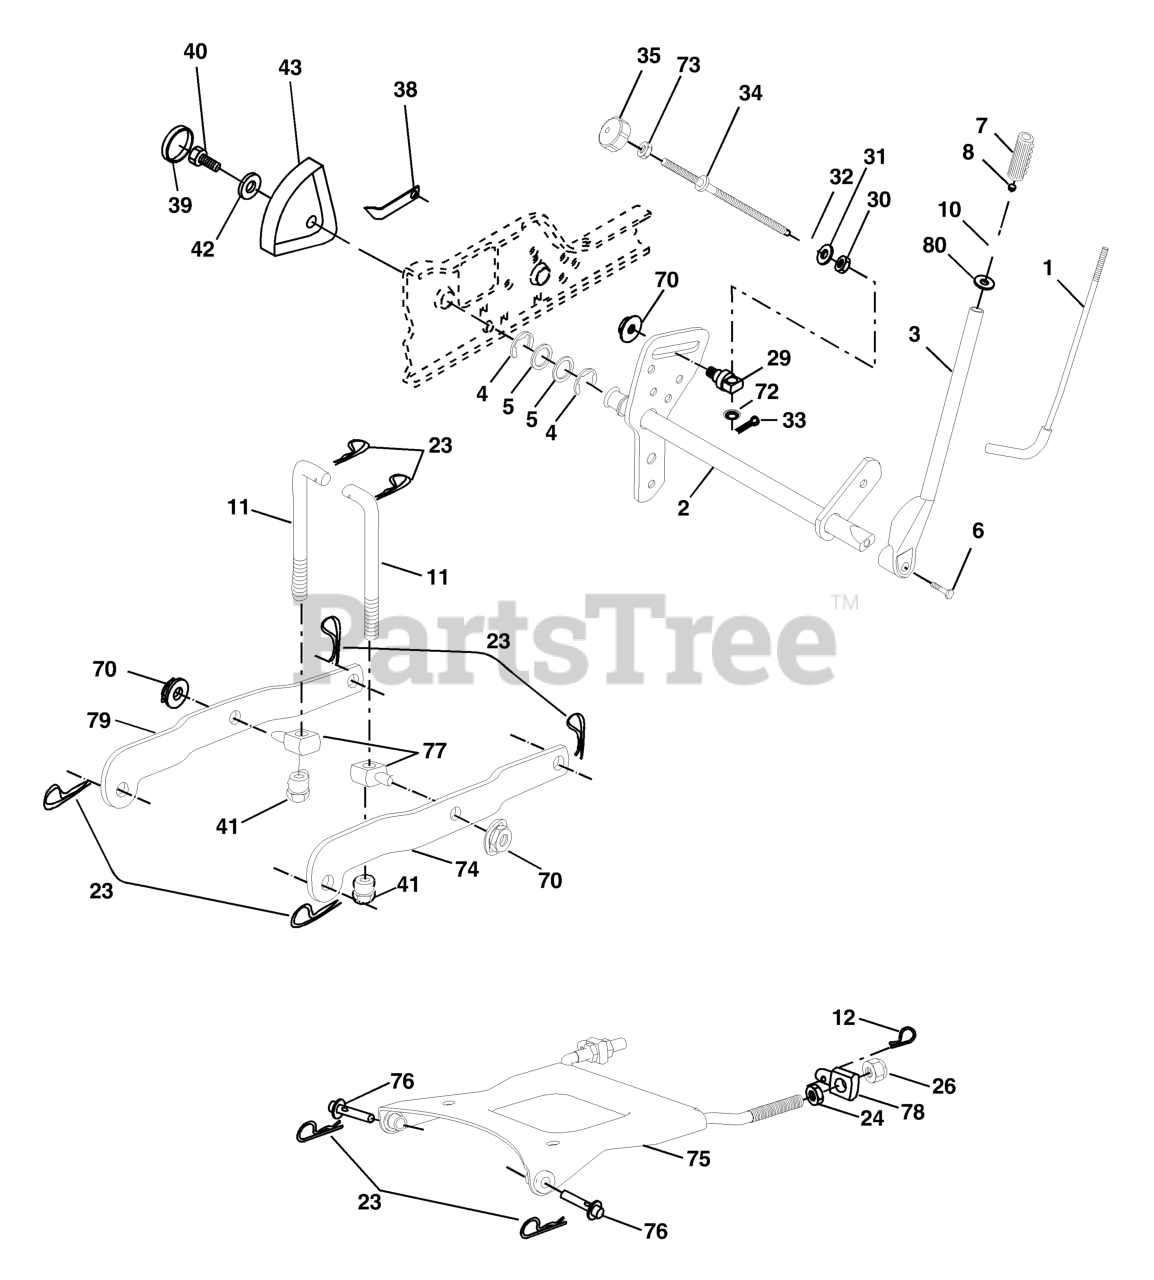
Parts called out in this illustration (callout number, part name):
1	LEVER ROD LT
2	SHAFT ASM., LIFT VGT
3	LEVER ASSY-LIFT RH
5	Washer 29/32 x 1-1/4 x 16 Ga.
6	Bolt, Fin Hex 3/8-16 x 1-1/2
7	GRIP HANDLE
8	PLUNGER BUT KIT
9	PLUNGER BUT KIT
10	SPRING**
11	LIFT LINK
12	SPRING RETAINER
13	ARM SUSP. REAR LH
23	RETAINER-SPRNG RB
24	NUT.HEX.JAM.1/2-13
26	NUT LTV
32	SPRING.COMP.INF.H
33	COTTER PIN
34	ROD.LIFT.ADJUSTABLE
35	KNOB INF 3/8-16
38	POINTER, HEIGHT INDICATOR(2 2)
40	SCREW 5/16-18X1
41	NUT, LIFT LINK 7/16-20
43	HEIGHT INDICATOR
70	NUT
72	NUT PUSH M
73	NUT
74	ARM SUSP REAR RH
75	PLATE ASM SUSP FRONT
76	PIN.FLANGE
80	WASHER
